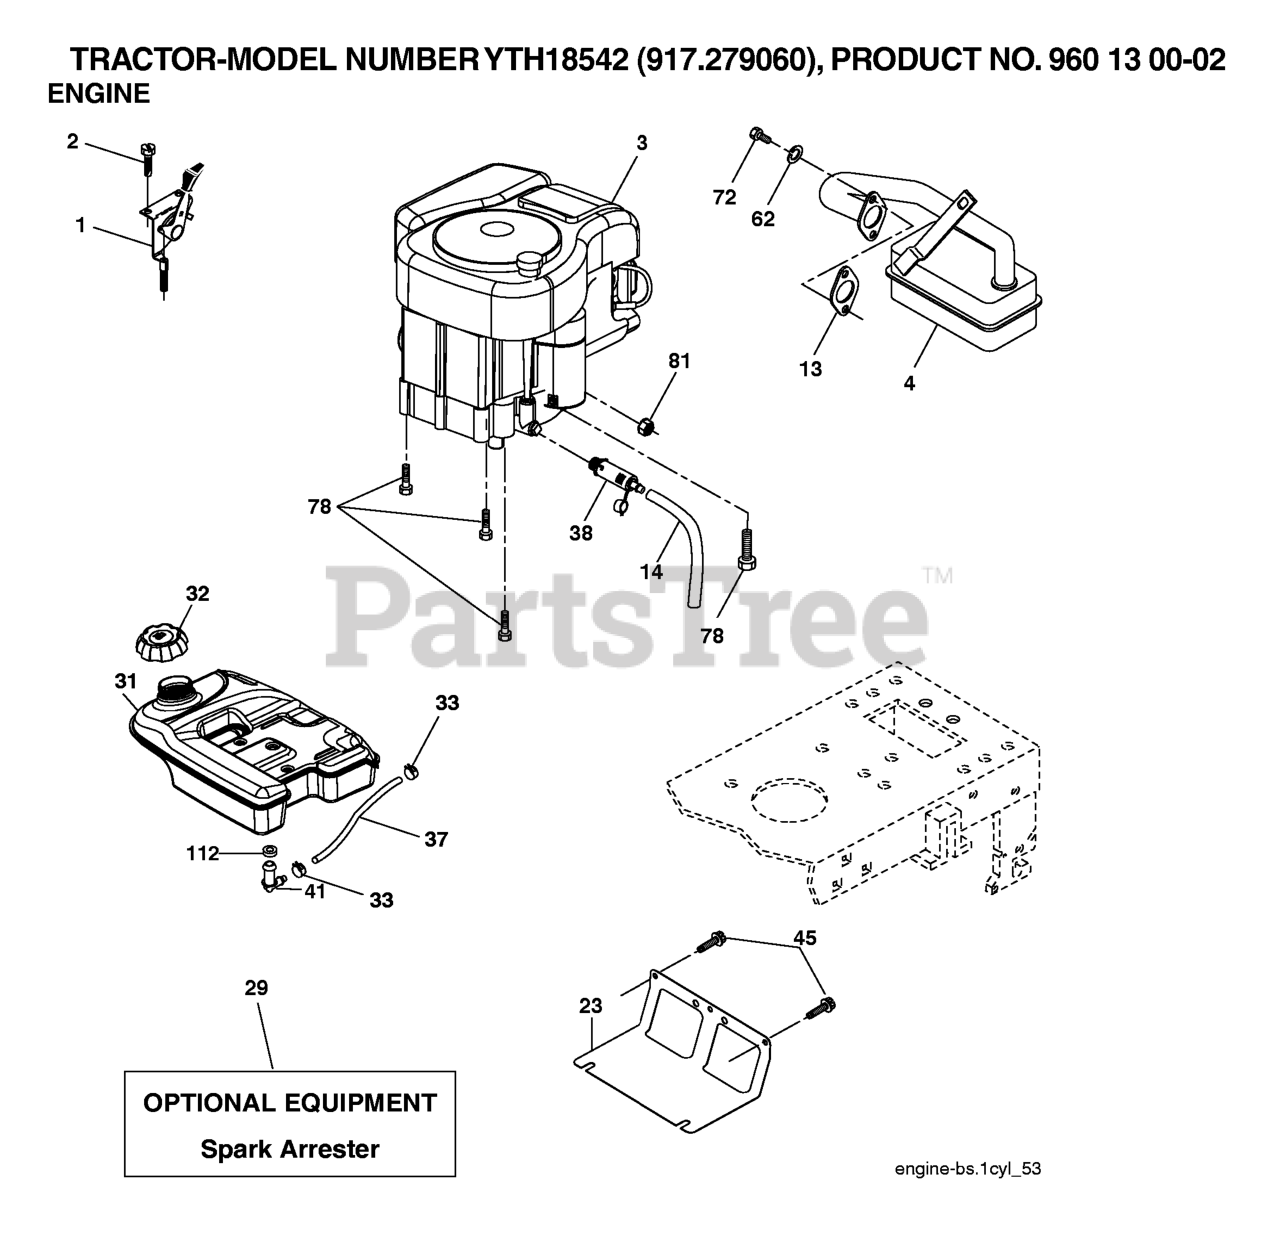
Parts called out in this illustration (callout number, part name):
1	CONTROL.THROTTLE.LT/YT
2	SCREW
4	MUFFLER.LT.BRIGGS.14HP.IC/OHV
13	REPL BY 532 27 22-93
14	TUBE, DRAIN OIL ASM.
23	SHIELD.BROWNING.DBR.GUARD
29	KIT.SPARK ARRESTOR 794945 B&S
31	4.0 REAR FUEL TANK
32	TANK CAP
33	HOSE CLAMP
37	REPL BY 532 00 85-43
38	PLUG DRAIN OIL EASY
41	STEM FUEL TANK
45	SCREW, 3/8-16X3/4
72	SCREW
78	SCREW.3/8-16
81	NUT
112	BUSHING OUTLET T
